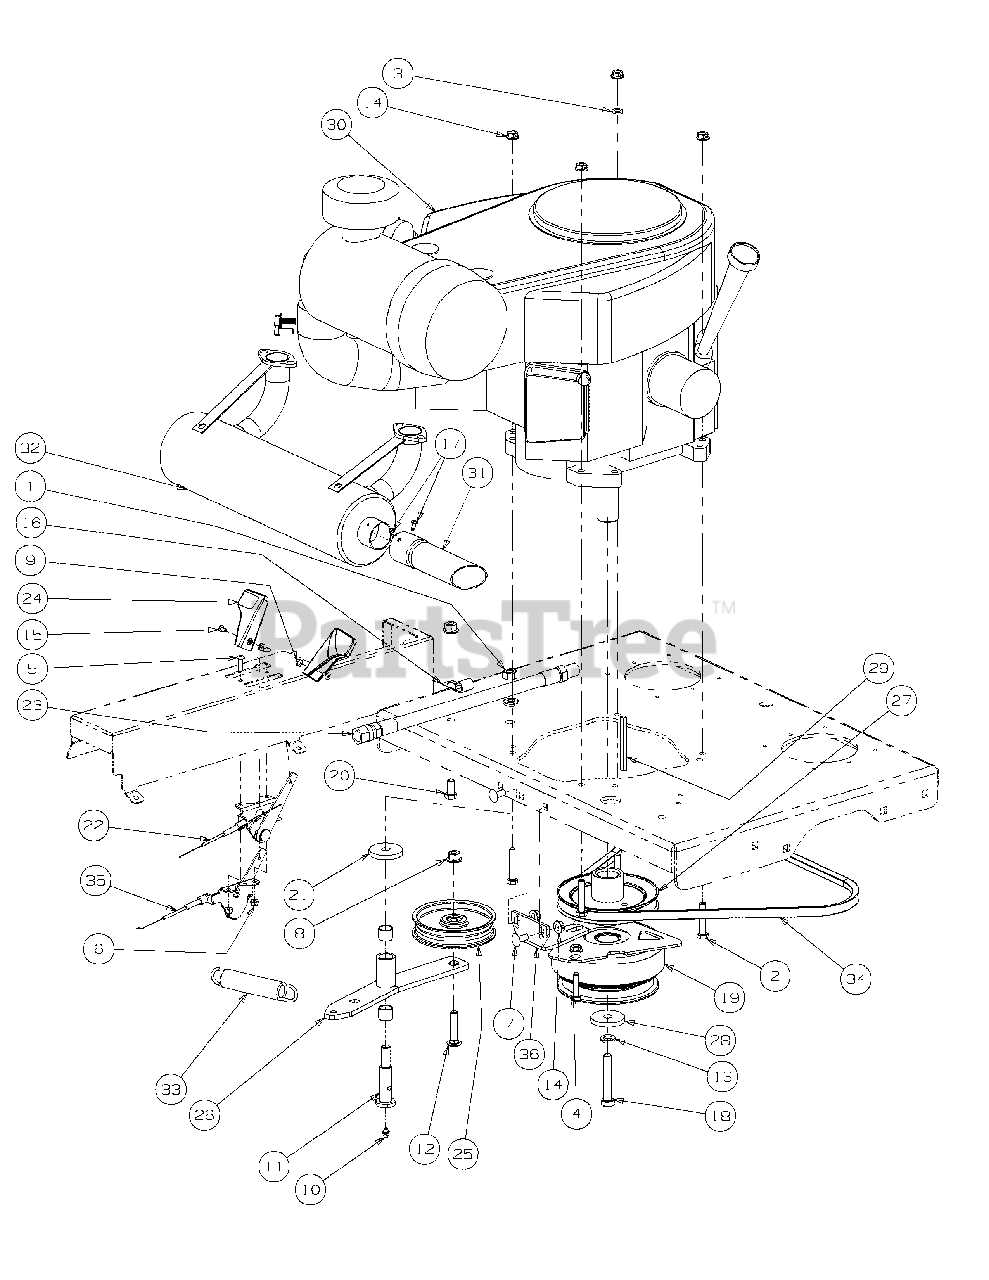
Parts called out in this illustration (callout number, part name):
1	Hex Nut, 7/16-14
2	HHCS, 5/16-18, 1-3/4
3	Flat Washer, .320 ID x .591 OD x .078
4	HHCS, 5/16-18 x 1-1/4
5	Round Hd. Machine Screw, 10-32 x 3/4
6	Lock Nut, Nylon Insert, 10-32
7	Carriage Bolt, 5/16-18 x .75
8	Flange Lock, Hex Nut, 3/8-16
9	Nut Washer, W/Star, 8-32
10	Grease Fitting, 1/4-28 x 3/16
11	Shoulder Screw, 7/16-14
12	Hex Carriage Screw, 3/8-16, 1.75
13	Lock Washer, 7/16
14	Hexflange Lock Nut, 5/16-18
15	Machine Screw, 8-32, .375
16	Clip, Heat Shield Cable
17	Screw, #8-32 x 0.375
18	Capscrew, 7/16-20 x 2.50
19	Clutch Brake, 1.125 ID
20	Hex Cap Screw, 3/8-16, .750
21	Flat Washer, 7/16 ID x 1.75 OD x .25
22	Choke, Control Cable, 43.0
23	Oil Drain Hose
24	Control Throttle Knob
25	Flat Pulley with Flanges
26	Engine Idler Arm Assembly Includes
27	Pump Drive Pulley
28	Flat Washer, 7/16 ID x 1.75 OD x .25
29	Key, 1/4 x 1/4 x 3
30	23HP Engine, Kawasaki
31	Muffler Accessory Exhaust Tube
32	Muffler Accessory, Kawasaki
33	Extension Spring, .98 OD x 5.00
34	V Belt, A Section x .48.5
35	Throttle, Control Cable, 39.0
36	Retainer Clutch Assembly, Ogura Bolt (pin) style
